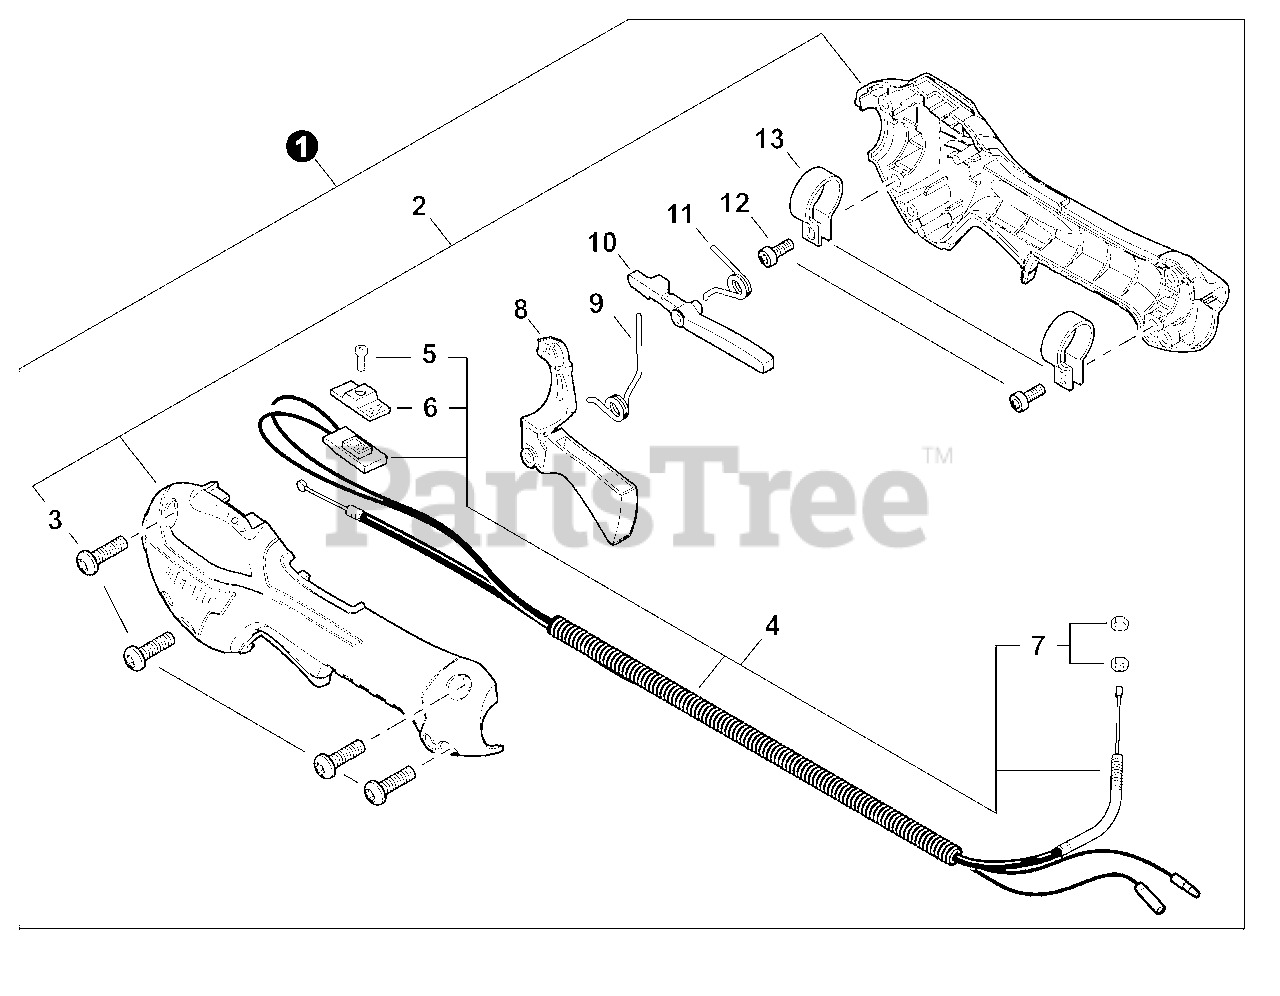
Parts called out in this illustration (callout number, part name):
1	CONTROL HANDLE ASSY
2	CONTROL HANDLE KIT
3	BOLT, TORX 5×16
4	CABLE ASSY, CONTROL
5	SCREW 3×10
6	KNOB, SWITCH - ORANGE
8	TRIGGER, THROTTLE
9	SPRING, TORSION
10	LEVER, THROTTLE LOCKOUT
11	SPRING, TORSION
12	BOLT, TORX 5×16
